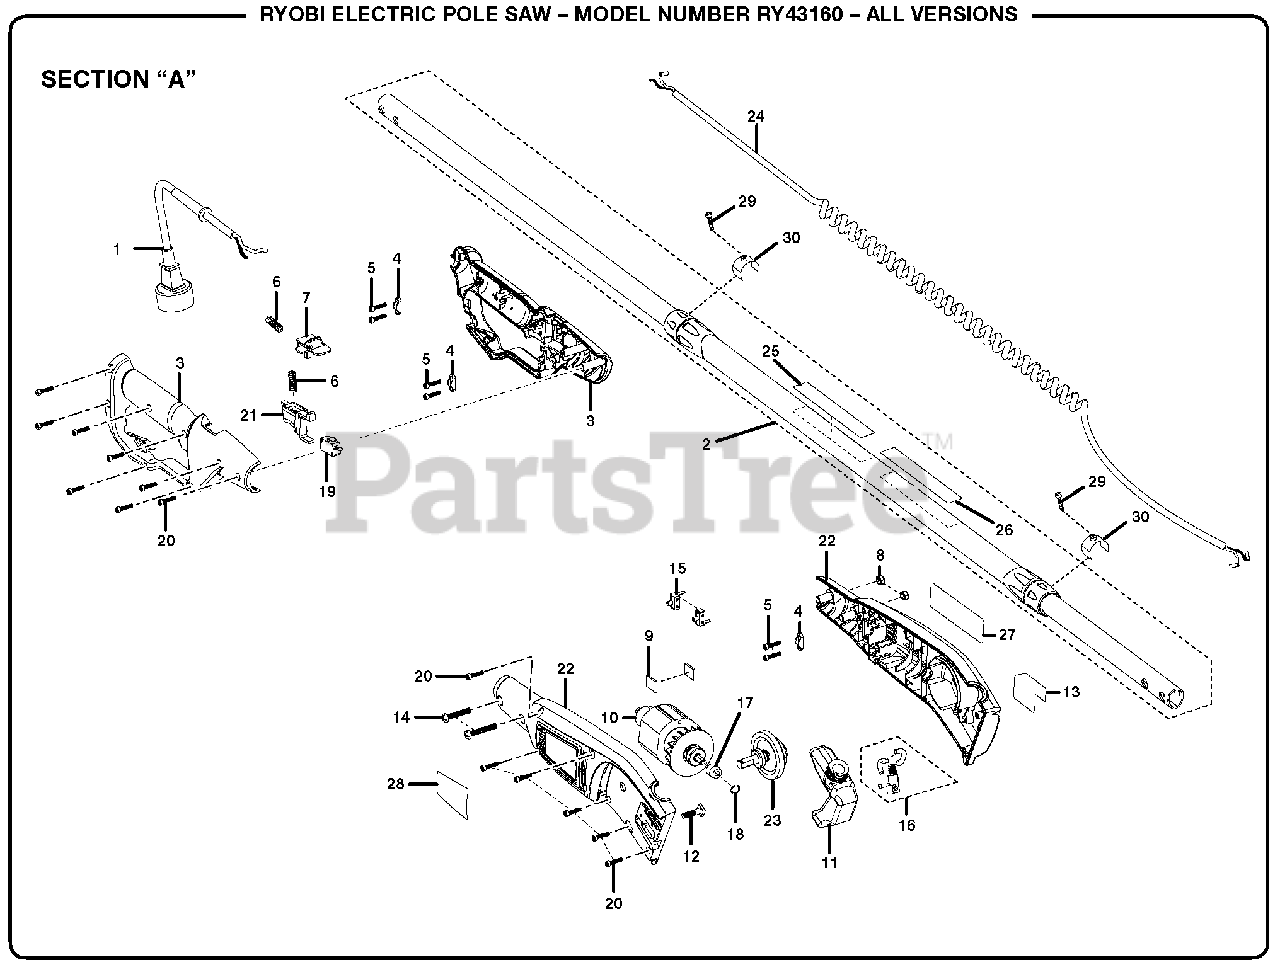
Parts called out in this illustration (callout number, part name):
1	Power Cord
2	Pole Assembly
3	Handle Assembly
4	Cord Clamp
5	Screw (M4 x 12 mm)
6	Compression Spring
7	Lock-off Button
8	Lock Nut (M6)
9	Rubber Pad
10	Motor Assembly
11	Oil Tank Assembly
12	Bar Stud (1/4-28)
13	Data Label (English)
14	Screw (M6 x 32 mm)
15	Brush Assembly
16	Oil Pump Assembly
18	Retaining Ring
20	Screw (M4 x 18 mm)
22	Housing Assembly
23	Output Shaft Assembly
24	Spring Cord Assembly
25	Warning Label
26	Data Label (French/Spanish)
27	Logo Label (Left)
28	Logo Label (Right)
29	Screw (M3 x 4 mm)
30	Lock Spring
